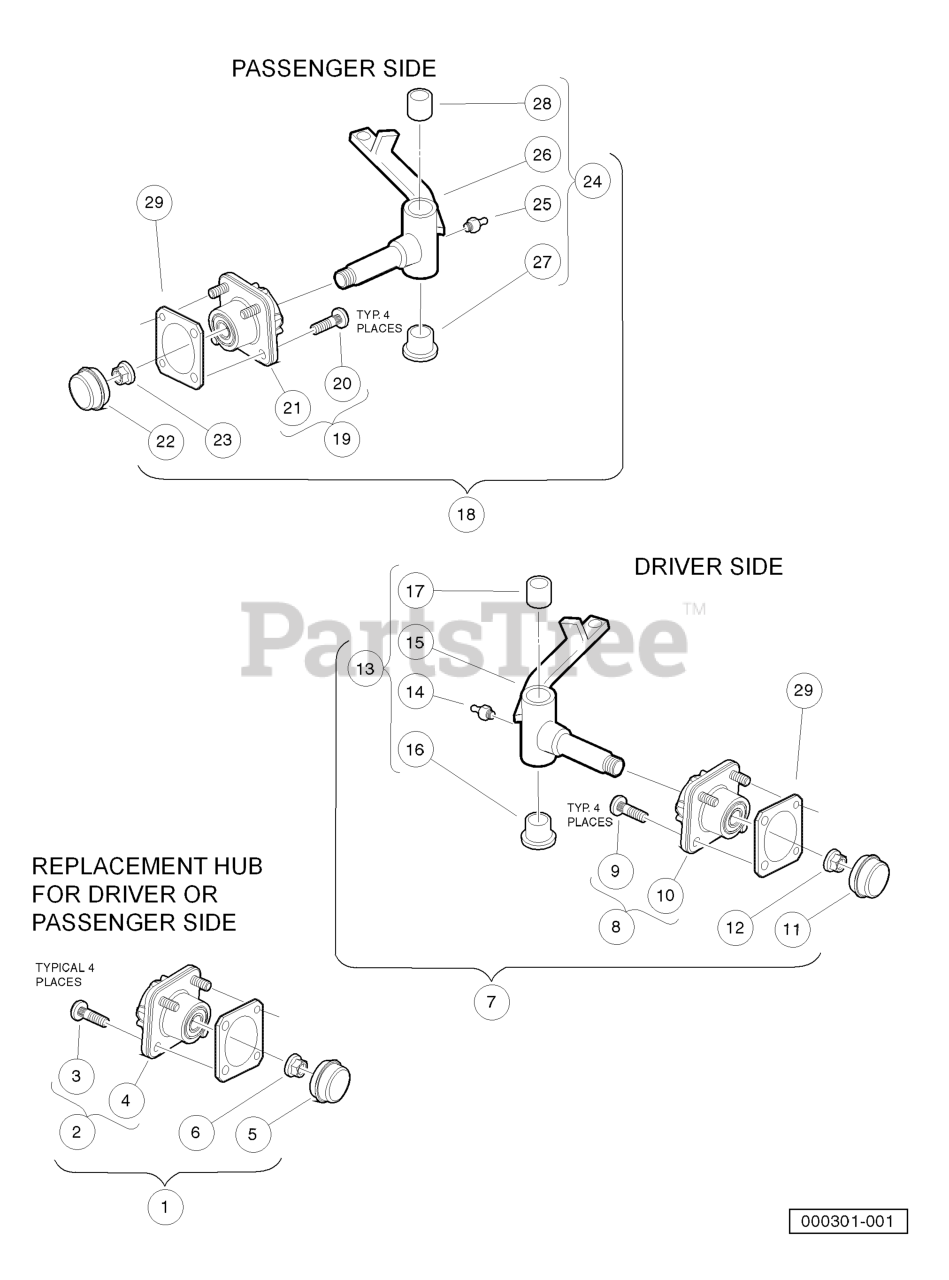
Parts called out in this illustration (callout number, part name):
1	REPLACEMENT KIT, FRONT HUB
2	Front Hub Assembly, Ball Bearing
3	LUG STUD, 1/2-20 UNF, 4037 STL
4	Hub, Front
5	CAP, FRONT HUB
6	HEX NUT, LOCKING FLANGE, M14X2
7	Asm, Front Hub And Spindle, Left-Hand
9	LUG STUD, 1/2-20 UNF, 4037 STL
10	Hub, Front
11	CAP, FRONT HUB
12	HEX NUT, LOCKING FLANGE, M14X2
13	ASM, SPINDLE, LH
14	FITTING, 1/4-28 THRD FRM GREAS
15	Sub-Assembly, Spindle, Left-Hand
16	BUSHING, FLANGED BROZE
17	BUSHING BRONZE SPINDLE
18	Asm, Front Hub And Spindle, Right-Hand
19	Front Hub Assembly, Ball Bearing
20	LUG STUD, 1/2-20 UNF, 4037 STL
21	Hub, Front
22	CAP, FRONT HUB
23	HEX NUT, LOCKING FLANGE, M14X2
24	ASM, SPINDLE, RH
25	FITTING, 1/4-28 THRD FRM GREAS
26	Sub-Assembly, Spindle, Right-Hand
27	BUSHING, FLANGED BROZE
28	BUSHING BRONZE SPINDLE
29	SPACER, WHEEL
